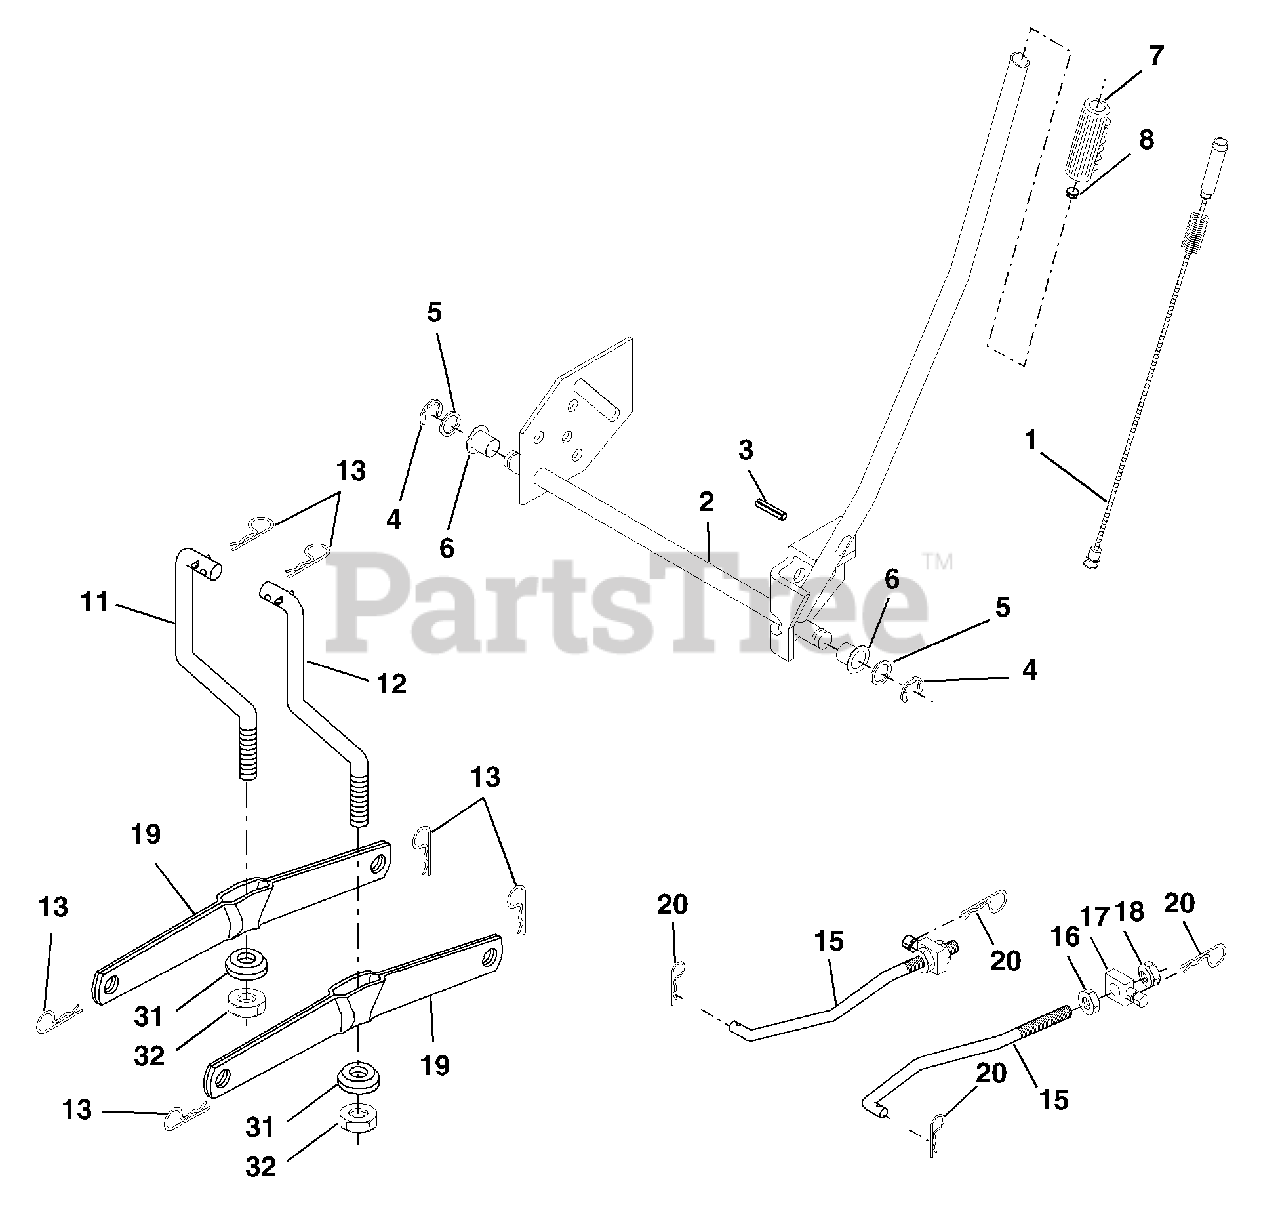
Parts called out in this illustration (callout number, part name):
1	Wire Asm Inner W/plunger
2	Shaft Asm Lift
3	Pin Groove 1 500 Zinc
4	E Ring #5133-62
5	Washer Pltd 21/32 X 1 X 21ga
6	Bearing Nylon Blk 629 Id
7	Grip Handle Fluted Blk
8	Button Plunger Red
11	Link Lift LH
12	Link Lift RH
13	Retainer Spring
15	Link Front
16	Nut Jam Hex 1/2-13 Unc
17	Trunnion Blk Zinc
18	Nut Lock w/Wsh 1/2-13 UNC
19	Arm Suspension Rear
20	Retainer Spring Zinc
31	Bearing Pvt Lift
32	Nut Crownlock 3/8-24
